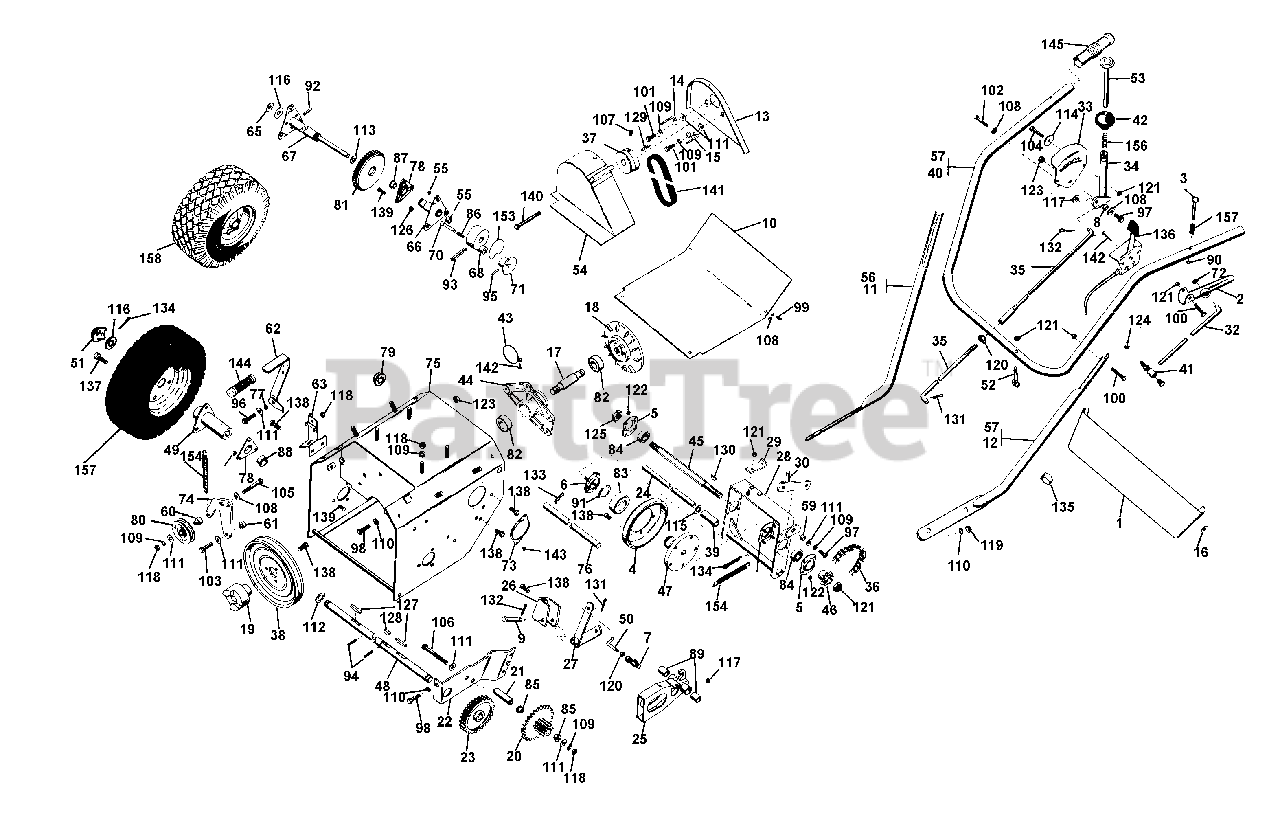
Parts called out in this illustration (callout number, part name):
1	HANDLE BAR PANEL
2	CLUTCH HANDLE
3	CLUTCH LOCK PIN
4	FRICTION DISC
5	BEARING FLANGE
6	BEARING FLANGE
7	BALL JOINT
8	SPACER BUSHING .5 X .32 X .21
9	CLEVIS PIN
10	BOTTOM COV
11	R H LOWER HANDLE BAR
12	L H LOWER HANDLE BAR
13	INNER BELT GUARD
14	R H BELT FINGER
15	L H BELT FINGER
16	HANDLE BAR WASHER
17	SPINDLE
18	DRIVE PLATE
19	JAW COUPLING
20	PINION & SPROCKET
21	PINION STUB SHAFT
22	SUPPORT BRACKET
23	SPUR GEAR, FELLOWS 35T .750 ID
24	BRACKET PIN
25	SLIDING FORK
26	LEVER BRACKET
27	TRANSFER LEVER
28	DISC BRCKT
29	NEUTRAL CATCH
30	THROWOUT LEVER
31	LOWER SHIFT ROD
32	CLTCH ROD
33	SHIFT QUADRANT
34	SHIFT HANDLE
35	SHIFT ROD
36	ROLLER CHAIN
37	ENGINE SHEAVE
40	UPPER HANDLE BAR
41	BALL JOINT
42	SHIFT BALL
44	BEARING HOUSING
45	HEX SHAFT
46	9 TOOTH SPROCKET
47	FRICTION DISC HUB
48	AXLE SHAFT
49	WHEEL HUB
50	CONNECTING LINK
51	HUB CAP
52	ROD HANGER EYEBOLT
53	SHIFT RELEASE HANDLE
54	OUTER BELT GUARD
55	HYDRAULIC DRIVE FITTING
56	R H LOWER HANDLE BAR
57	L H LOWER HANDLE BAR
58	UPPER HNDLBAR PLATED
59	SPACER BUSHING .5 X .32 X .163
60	BEARING SPACER
61	SHOULDER SPACER
62	CLTCH LEVER
63	CLTCH BRCKT
64	CARB COVER
65	PUSHNUT
66	L H AXLE
67	R H AXLE SHAFT
68	LOCKOUT HUB
69	CARBURETOR COVER
70	PIN
71	KNOB
72	RATCHET PLATE
74	IDLER ARM
75	TRACTOR FRAME
76	FORK SHAFT
77	SPACER .50 X .32 X .42
78	SUPPORT, BEARING
79	CAP, .50 ROD YWZC
80	IDLER
81	MOUNT, TRANSMISSION (T.T)
82	BRG-BALL .750X1.750X.50
83	BRG-N-THRST 1.26X2.18X.63
84	BRG-BALL .500X1.375X.437
85	BSHG-FLG .625X.750X.500X.875BR
86	BSHG-SLV .562X.625X.625 BRZ
87	BSHG-FLG.875X1X.625X1.250 BR
88	BSHG-FLG .750X1.000X.625X1.250
89	BSHG-SLV .500X.625X.500 BR
90	RG-RTNG-EXT .250X.031
91	RG-RTNG-EXT 1.250X.050
92	PIN-ROLL .188X1.25
93	PIN-ROLL .250X1.25
94	PIN-ROLL .188X1.00
95	PIN-ROLL .093X1.00
96	BLT-HEX .31-18X1.00 PL GR 2
97	BLT-HEX .31-18X.75 PL GR2
98	BLT-HEX .38-16X.75 PL GR2
99	BLT-HEX .25-20X.50 PL GR2
100	BLT-HEX .25-20X1.50 PL GR5
101	BLT-HEX .31-24X.75 PL GR5
102	BLT-HEX .25-20X1.25 PL GR5
103	BLT-HEX .31-18X1.25 PL GR2
104	BLT-HEX .25-20X1.25
105	BLT-HEX .31-18X1.75 PL GR2
106	BLT-HEX .31-18X2.75 PL GR2
107	SCR-SET .32-18X.38 SKHCUPNL OH
108	WSHR-LK .250X.077 HVY PL
109	WSHR-LK .312X.097 PL HVY
110	WSHR-LK .375X.115 HVY PL
111	WSHR-FL-STL .38X.875X.083 PL
112	WSHR-FL-STL .755X1.375X.125
113	WSHR-FL-STL .880X1.380X.062
114	WSHR-FL-STL .281X1.250X.048PL
115	WSHR-FL-STL .505X.875X.024 PL
116	WSHR-FL-STL .755X2.000X.125
117	WSHR-FL-STL.406X.812X.065PL
118	NUT-HEX .312-18
119	NUT-HEX .375-16
120	NUT-HEX .312-24 PL
121	NUT-LK-CTR .250-20 PL
122	NUT-LK TOP 10-24 PL
123	NUT-LK .312-18 GR A PL
124	NUT-LK-CTR .312-24 PL
125	NUT-LK-CTR .50-20 PL
126	NUT-LK-FLG .250-20 PL
127	KEY-FTHR .188X1.25X.187 SAE
128	KEY-WDRF .25X.750X.313 SAE91
129	KEY-SQ .188X1.0X.188 SAE 8630
130	KEY-WDRF .125X.625X.250 SAE5
131	PIN-COTR .09X.75 PL
132	PIN-COTR .12X1.0 PL
133	PIN-HAIR INT .08X.38X1.42 YWZC
134	PIN-COTR .12 X 1.25 PL
136	THROTTLE CONTROL
137	BLT-WHL .50-20X.50 GR5 PL
138	BLT-SERHFWH .31-18X.50 PL
139	SCR-SLTR-SERNK .25-20X.62 PL
140	BLT-HFWH .31-24X3.62 PL
141	V-BELT, SAE 380-RAW EDGE
142	SCR-TAP 10-12X.50 CRPH PL A
143	SCR-TAP 10-24X.25 CRSLPH PL 1A
145	GRIP
146	SNO-THRO HELICON PATENT LABEL
147	CLUTCH LABEL
148	CARB. COVER LABEL
149	SNO THRO SHIFT LABEL
150	5 H P ENGINE DECAL
151	6 H P ENGINE DECAL
152	7 HP ENGINE DECAL
153	DIFFERENTIAL LOCK LABEL
154	SG-TENS .125X.437X5.5 WLD 20
155	SG-COMP .028X.34X1.062 WLD75
156	SG-COMP ??X.44X?? WLD 10
157	TIRE & WHEEL ASSEMBLY GOODYEAR
157	TIRE 4.10/3.50X6
157	TIRE 4.10/3.50X6 2PLY
157	WHL 6 IN O.D.
158	TIRE & WHEEL ASSEMBLY CARLISLE
158	TIRE 12.5/4.50-6
158	WHL 6 IN O.D.
